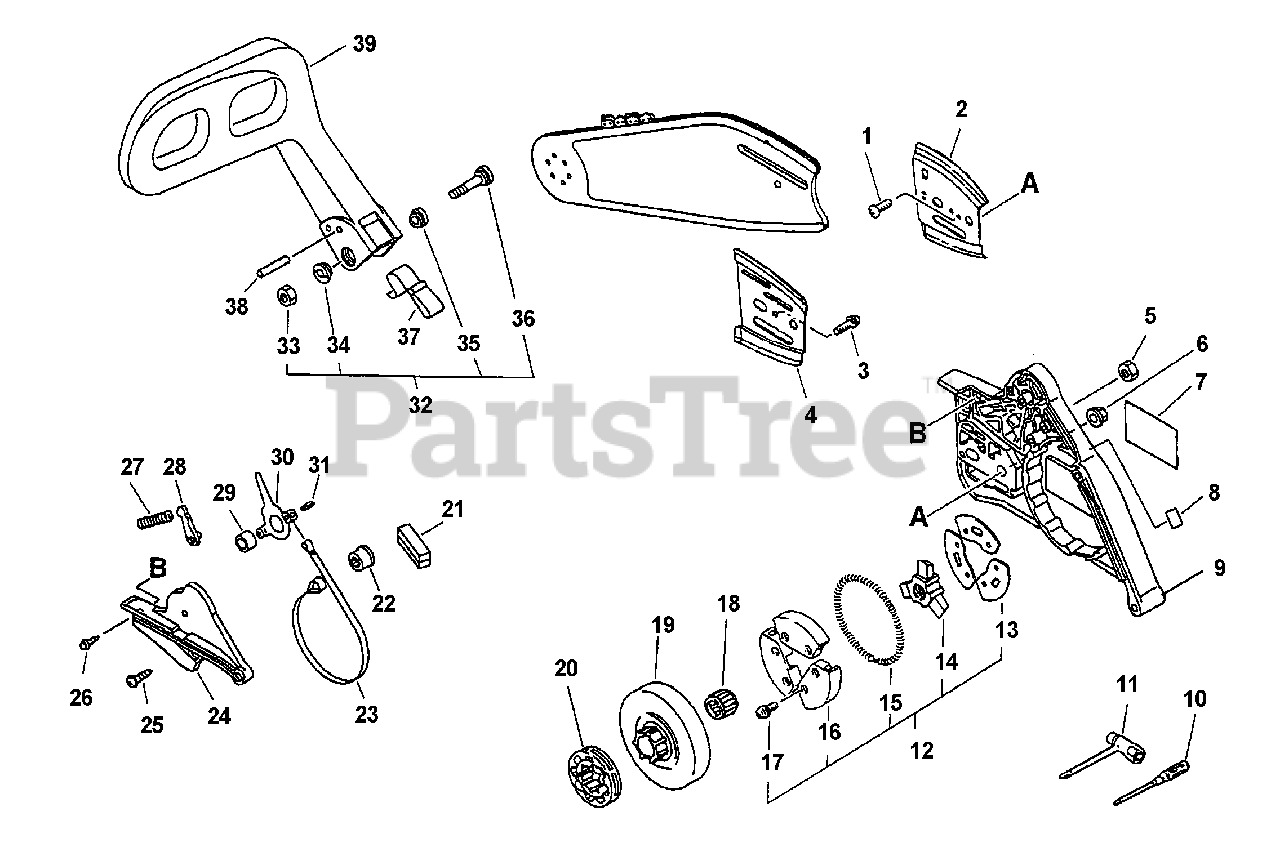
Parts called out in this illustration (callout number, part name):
1	SCREW - 3X6
2	PLATE, GUIDE - OUTER
3	SCREW - 4X8
4	PLATE, GUIDE - INNER
6	NUT - FLANGE
7	LABEL - ECHO
8	LABEL - CAUTION
9	GUARD, SPROCKET
10	SCREWDRIVER
11	T-WRENCH - 13X19mm
12	CLUTCH ASSY
13	PLATE, CLUTCH
14	HUB, CLUTCH
15	SPRING, CLUTCH
16	CLUTCH SHOE SET
17	SCREW - 4X6
18	BEARING, NEEDLE
19	DRUM, CLUTCH
20	SPROCKET, RIM
22	ADJUSTER, BRAKE BAND
23	BAND, BRAKE
24	COVER, BRAKE
25	SCREW - 3X18
26	SCREW - 4X12
27	SPRING, BRAKE
28	STOPPER, BRAKE
29	SPACER - 8
30	LEVER, BRAKE
31	PIN - SPRING -- 4X8
32	MOUNTING KIT
33	LOCKNUT - 5
35	COLLAR - 5
36	SCREW - 5X35
37	SPRING, RETURN
38	PIN - 3.5X26
39	LEVER, BRAKE
